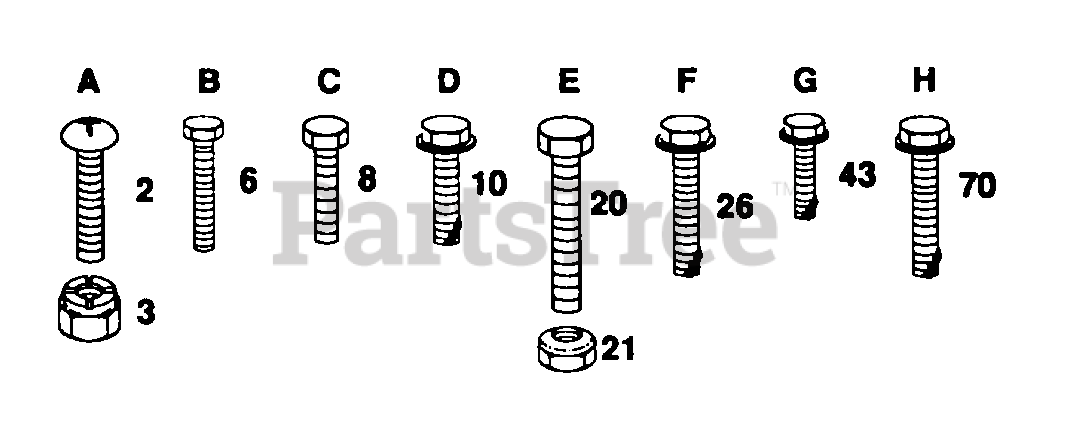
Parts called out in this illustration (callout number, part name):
3	"BOLT, SHOULDER LT"
8	"SUP,LVR,CLUTCH LT"
10	TANK.FUEL.LT.
20	E-RING
43	SPRING H
